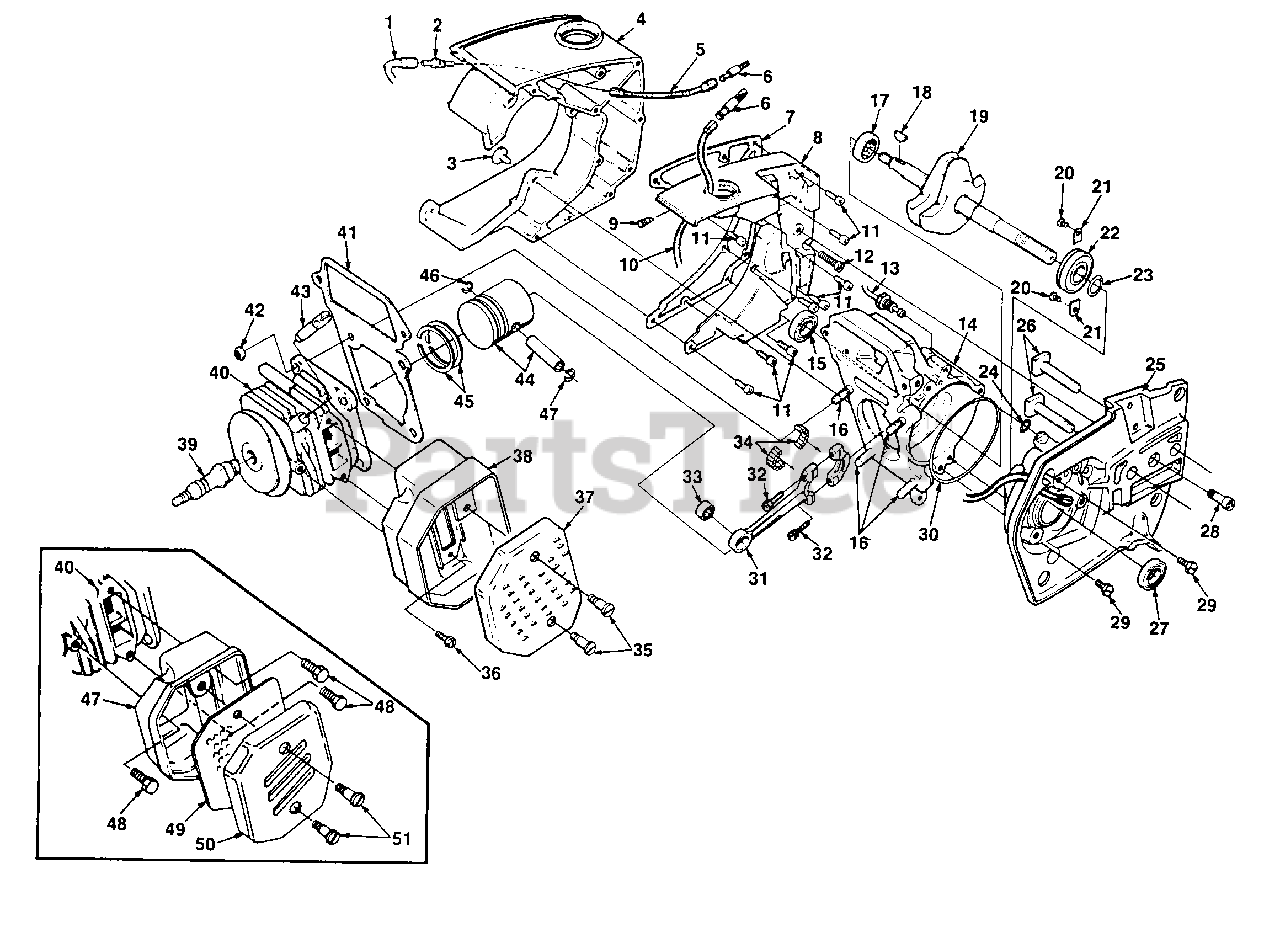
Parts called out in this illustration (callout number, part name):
1	LINE- Oil
2	FITTING- Oil line
3	SCREW- Retaining
4	TANK- Fuel & oil
5	LINE- Oil (pick up)
6	FILTER- Oil
7	GASKET- Fuel & oil tank
8	COVER- Fuel & oil tank
9	VALVE- Check
10	LINE- Oil
11	SCREW- Fil., 8-32 x 5/8
12	SCREW- Fil., 7-32 x 1 7/16
13	LINE- Oil
14	CRANKCASE
16	STUD- Cylinder
17	BEARING- Roller
18	KEY- Woodruff
19	CRANKSHAFT
20	SCREW- Bearing retaining
21	WASHER- Lock
22	BEARING- Ball
23	RING- Retaining
24	"O" RING
25	DRIVECASE
26	BOLT- Guide bar
28	SCREW- Fil., drivecase retainer
29	SCREW- Hex. 12-24 x 5/8
30	"O" RING
31	ROD- Connecting
32	SCREW- Cap, hex soc. hd.
33	BEARING- Needle
34	BEARING- Needle (Set of 28)
35	SCREW- Shoulder
36	SCREW- Hex. 10-32 x 3/8
37	CAP- Muffler
38	BODY- Muffler
39	SPARK PLUG
40	CYLINDER 1-9/16 dia.
41	GASKET- Cylinder
42	NUT- Hex 1/4-28
43	VALVE- Compression release
44	PISTON & PIN
45	PISTON RING
46	RING- Piston pin retaining
47	BODY- Muffler
48	SCREW- Hex, 10-32 x 3/8
49	BAFFLE- Muffler
50	CAP- Muffler
51	SCREW- Shoulder
